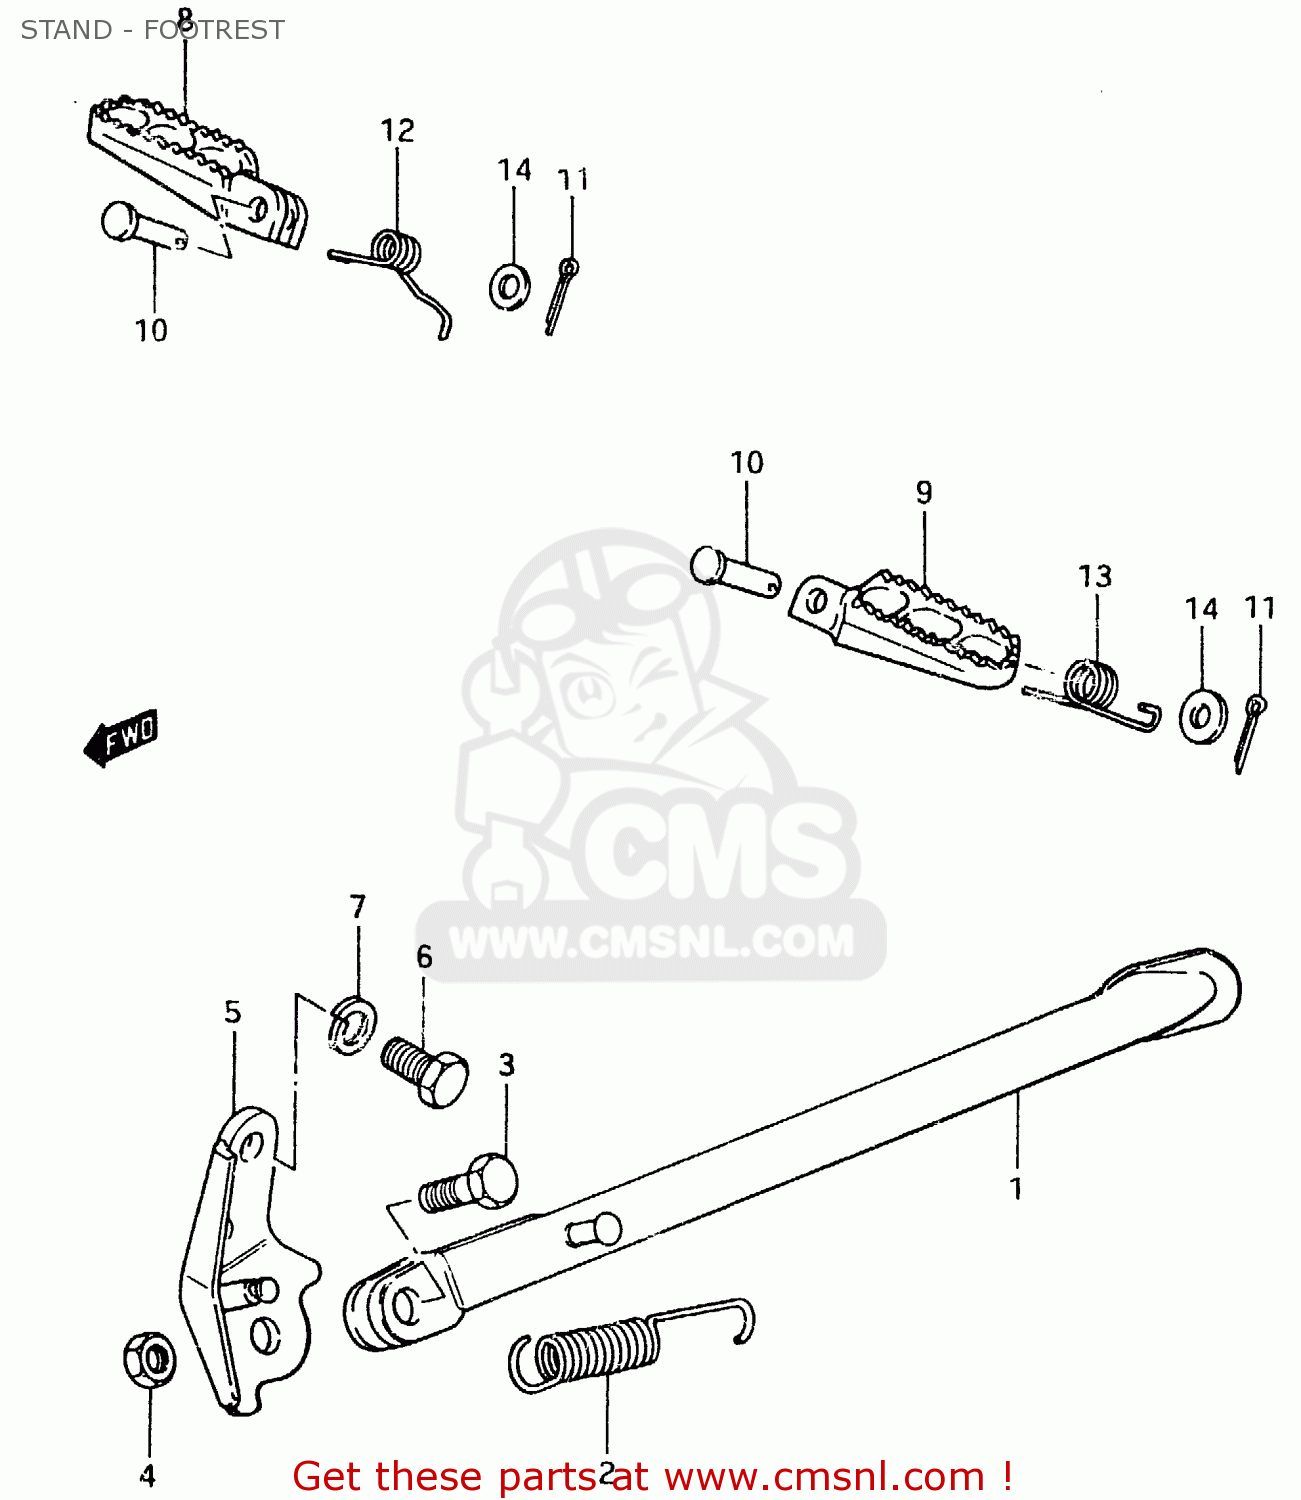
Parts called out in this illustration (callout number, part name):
1	STAND,SIDE
2	SPRING
3	BOLT(10X30)
4	NUT
5	BRACKET,SIDE STAND
6	BOLT(10X19)
7	LOCK WASHER
8	FOOTREST,RIGHT
9	FOOTREST
10	PIN
11	PIN 20X20
12	SPRING
13	SPRING,FOOTREST,LEFT
14	WASHER
